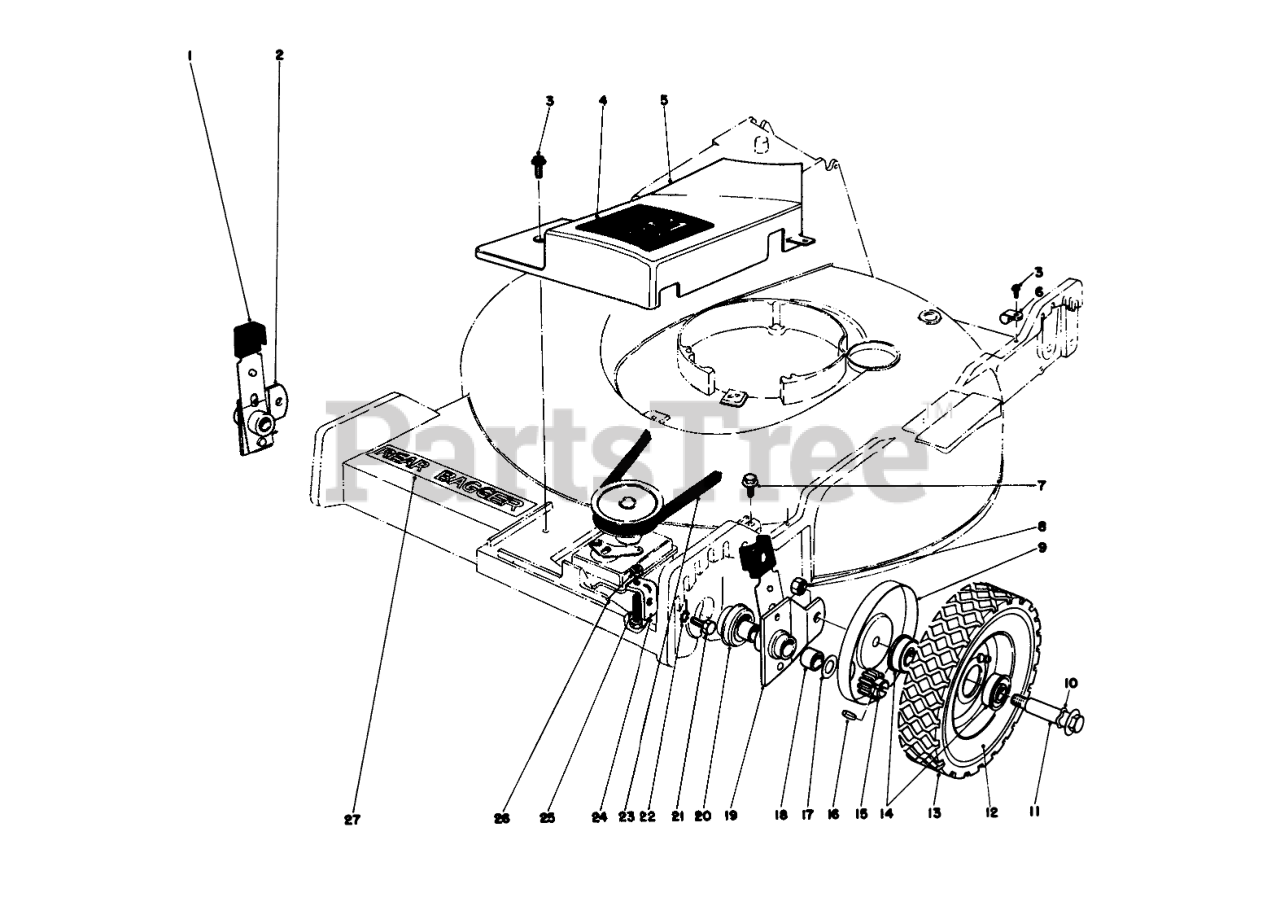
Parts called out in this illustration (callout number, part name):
1	KNOB-ARM
2	Pivot Arm Assembly (Incl. Ref. #18)
3	SCREW
4	Decal Belt Cover
5	BELT COVER
6	CLAMP-NYLON
7	SCREW-HWHTF
8	Nut
9	WHEEL COVER
10	SPRING WASHER
11	WHEEL BOLT
12	Wheel & Tire Assembly (Incl. Ref. #13 & 14)
14	BEARING-BALL
15	Pinion
16	PIN-GROOVED
17	WASHER-THRUST
18	BUSHING
19	Pivot Arm Assembly (Incl. Ref. #18)
20	End Cap
21	SCREW-HH
22	WASHER-LOCK
23	V-BELT
24	Bracket-Gear Box
25	SCREW
26	NUT-LOCK
27	DECK DECAL
